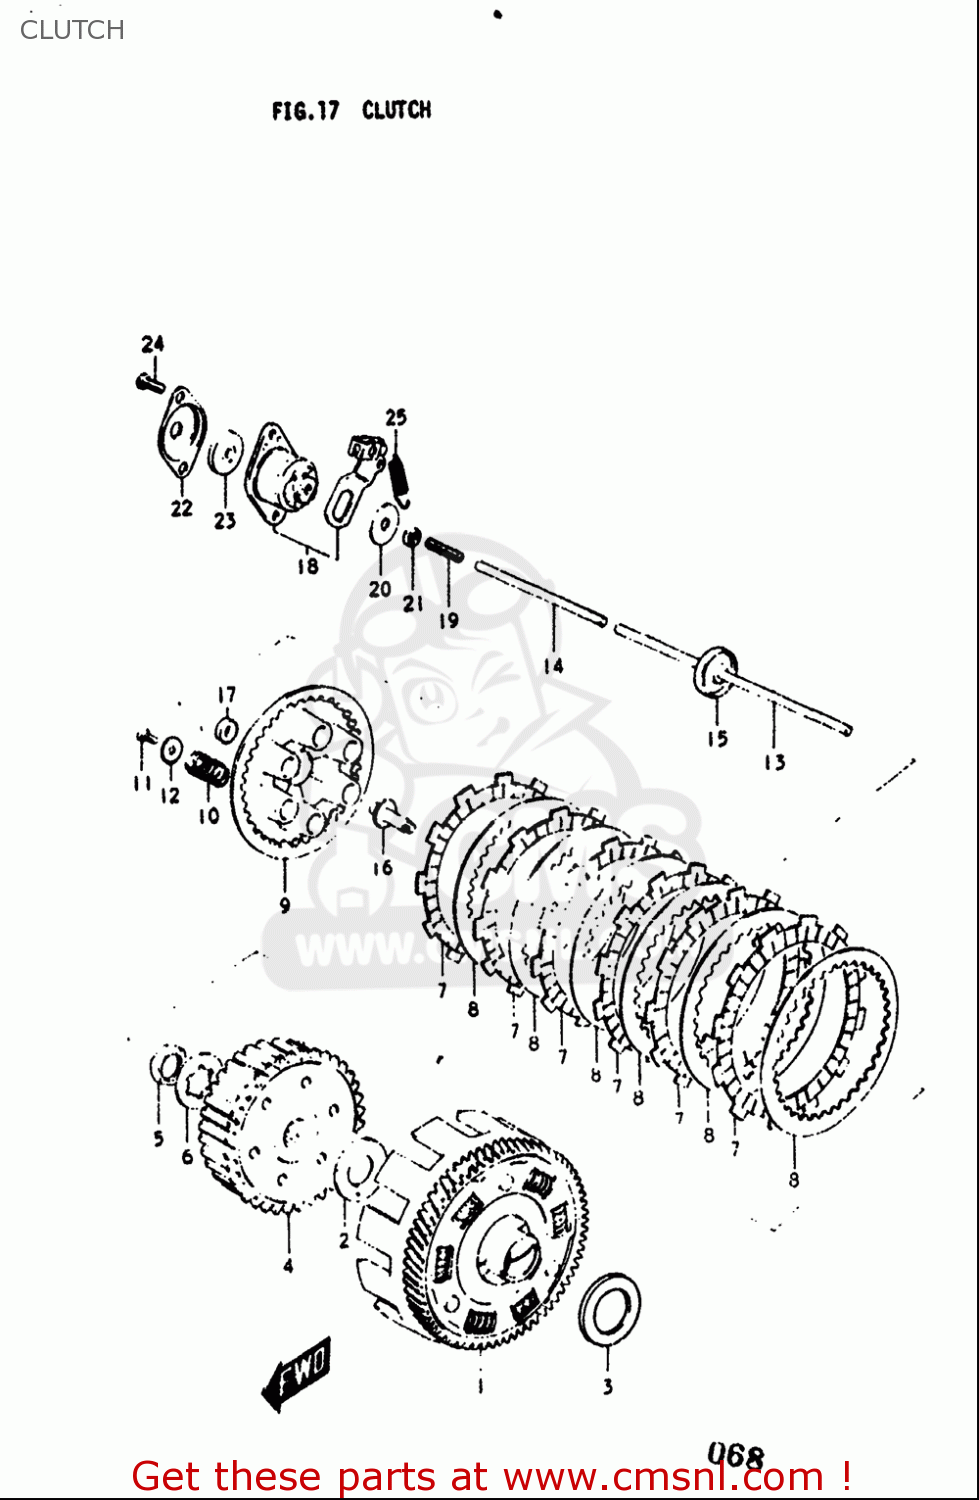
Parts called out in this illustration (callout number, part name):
2	WASHER(20X44X3)
3	WASHER(25X41X3)
5	NUT
6	WASHER,LOCK
7	PLATE,CLUTCH DRIVE(T:3.5) (NAS)
8	PLATE,CLUTCH DRIVEN(T:2.0) (NAS)
10	SPRING
11	BOLT
12	WASHER(6.5X20X1.6)
13	ROD,CLUTCH PUSH
14	ROD,CLUTCH PUSH NO.2
15	SEAL,OIL (6X30X5)
17	SEAL,OIL (10X17X5)
19	SCREW(6X25)
20	WASHER(6.5X24X1.2)
21	NUT
23	OIL SEAL
24	SCREW
25	SPRING
